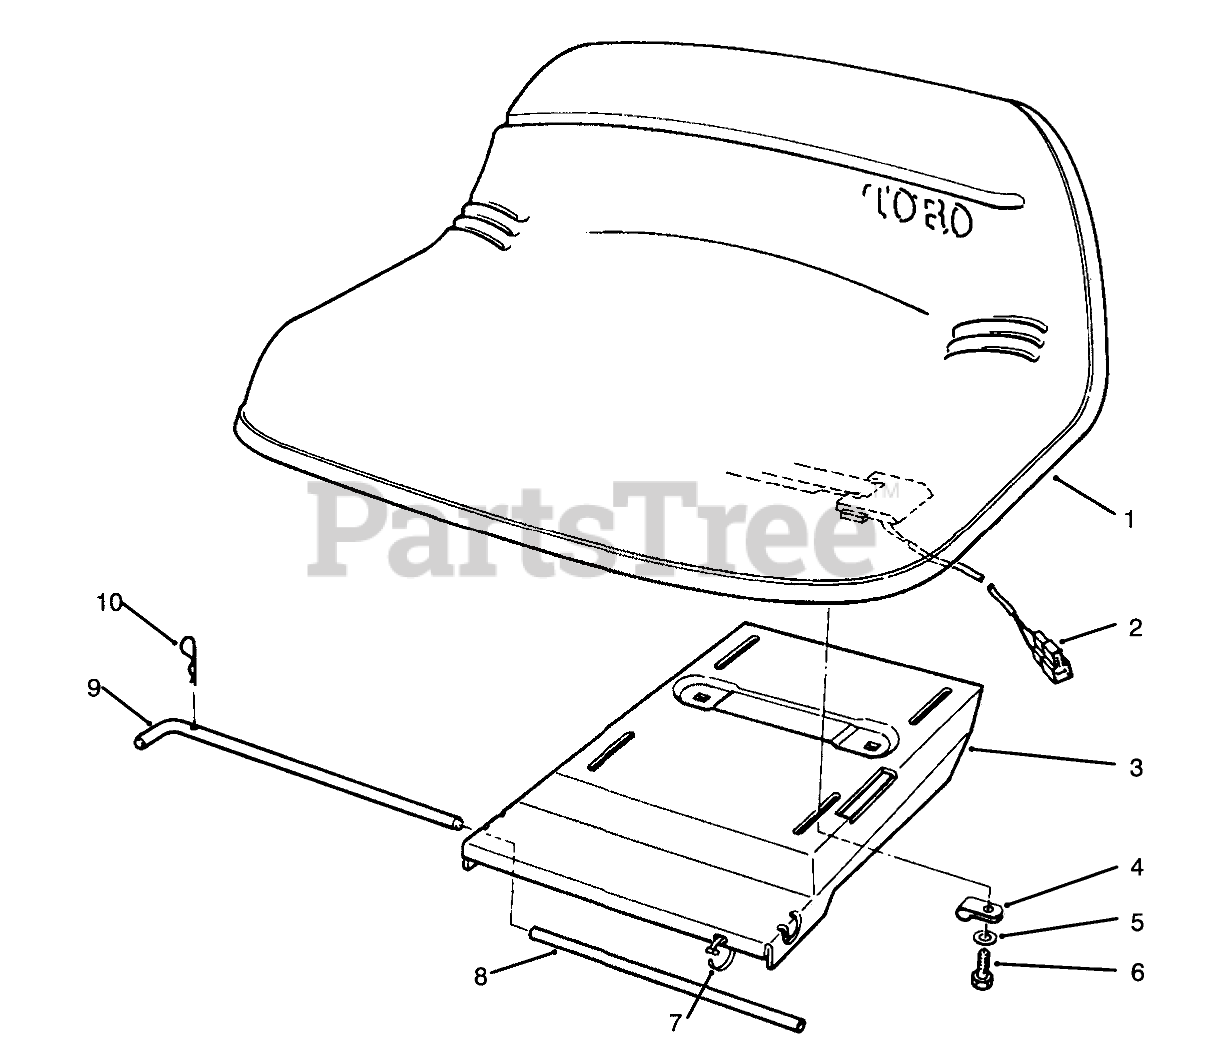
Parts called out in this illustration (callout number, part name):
1	Seat
2	SWITCH-SEAT
3	Base-Seat
4	CLAMP
5	WASHER-PLAIN
6	SCREW-HH
7	TIE-CABLE
8	TUBE-SEAT
9	ROD-SEAT BASE
10	PIN-COTTER
